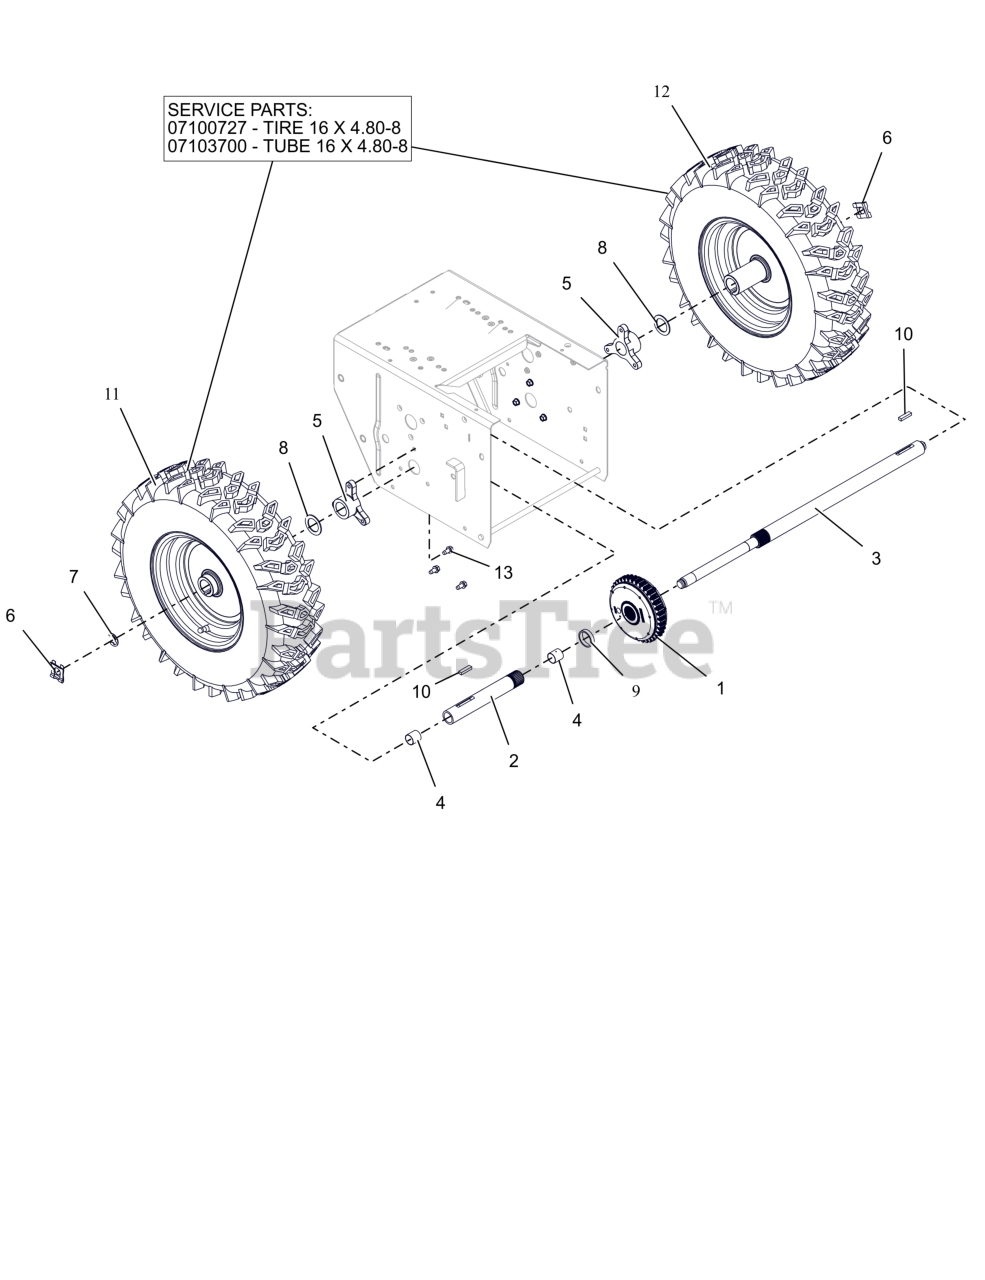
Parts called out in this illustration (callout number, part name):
1	DIFFERENTIAL, AUTOMATIC
2	AXLE, SHORT - W/BUSHINGS
3	AXLE,LONG-DELUXE AUTO DIFF
4	BSHG-SLV .706X.764X.75 BRZ
5	BUSHING, AXLE
6	CLIP, SNAP .625 DIA
7	RG-RTNG-EXT .625X.042
8	WSHR, FLT 1.010X1.505X.062 ZCC
9	BSHG, SLV 1.062X1.228X.268
10	KEY-RECT .25X.188X1.00
11	TIRE/WHEEL RH 16X4.8-8 DIFF T2
12	TIRE/WHEEL LH 16X4.8-8 DIFF T2
12	SNOW TIRE, 16/4.80-8 K478 DIRECTIONAL
12	TIRE TUBE, 16X4.80/4.00-8 4 PLY TR13 STRAIGHT VALVE
13	SCR-TAP .25-20X.50 HWH ZCC
